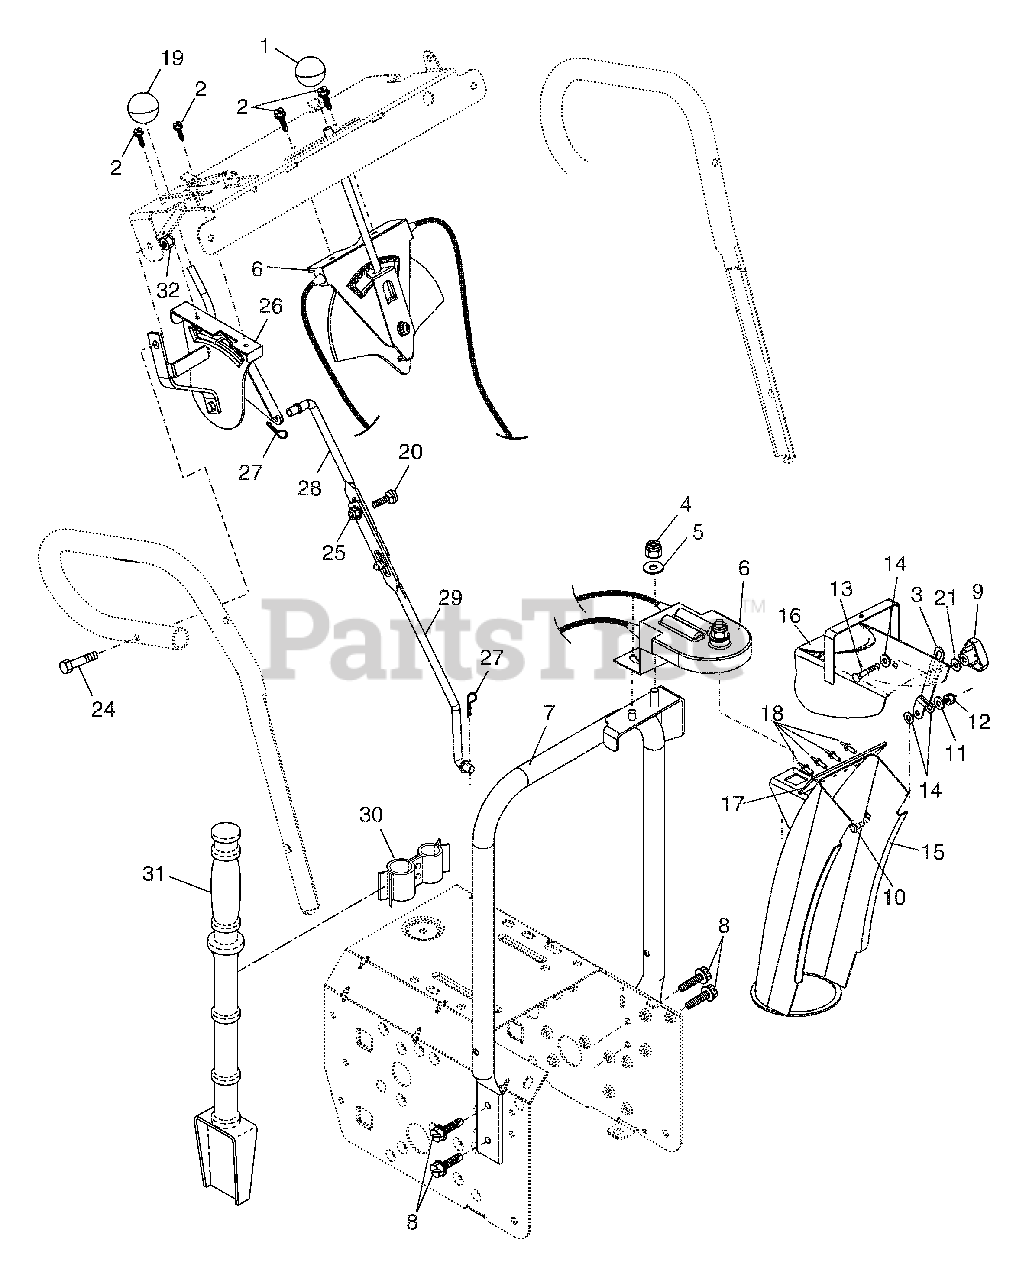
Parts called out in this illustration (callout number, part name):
1	Knob, Lever
2	Screw #10-24 x 5/8
3	Strap, Slotted
4	Nut, Lock 3/8-16
5	Washer, Flat 3/8
6	Control Assembly, Chute Rotater
7	Support, Pivot
8	Screw, Hex Head 5/16-18 x 3/4
9	Knob, Deflector
10	Bolt, Shoulder
11	Washer, Flat 1/4
12	Nut, Lock 1/4-20
13	Bolt, Carriage 5/16-18 x 5/8
14	Washer, Nylon
15	Chute Assembly
16	Deflector Assembly
17	Seal, Deflector
18	Rivet, Blind
19	Knob, Speed Control Lever
20	Bolt, Carriage 5/16-18 x 3/4
21	Washer, Flat 5/16
24	Screw, Hex Head 5/16-18 x 1-3/4
25	Nut, Lock 5/16-18
26	Lever Assembly, Speed Control
27	Retainer, Hairpin
28	Rod, Upper, Speed Control
29	Rod, Lower, Speed Control
30	Clamp, Clean-Out Tool
31	Tool, Clean-Out
32	Nut, Lock 5/16-18
